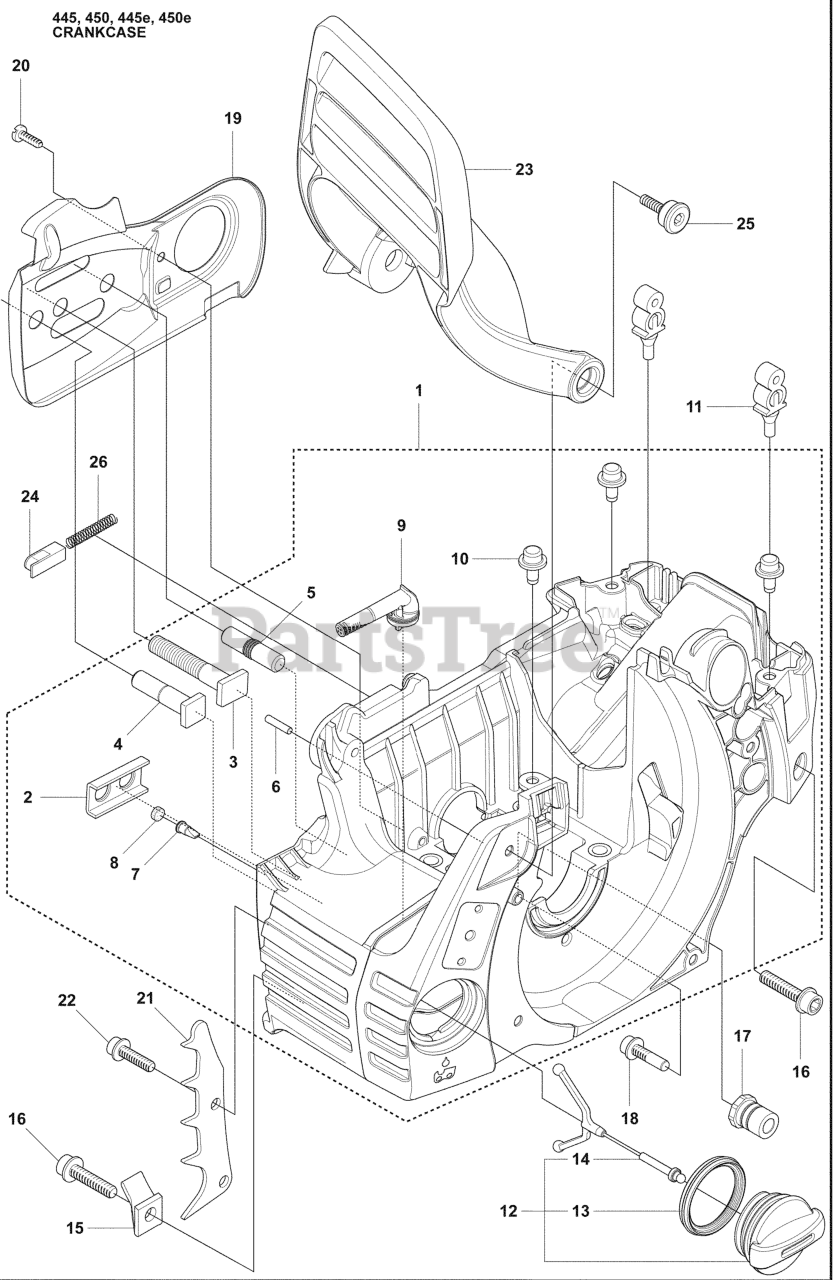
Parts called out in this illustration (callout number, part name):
2	STIFFENING PLATE
7	VALVE-CHECK (DUCKBILL)
8	PLUG
9	OIL SCREEN
11	SUPPORT
12	TANK CAP ASSY
13	SEALING
15	CHAIN CATCHER
16	SCREW IHSCFT
17	LATERAL SUPPORT
18	SCREW IHSCFT
19	CHAIN GUIDE PLATE
23	HAND GUARD
25	SCREW
26	LOCK SPRING
